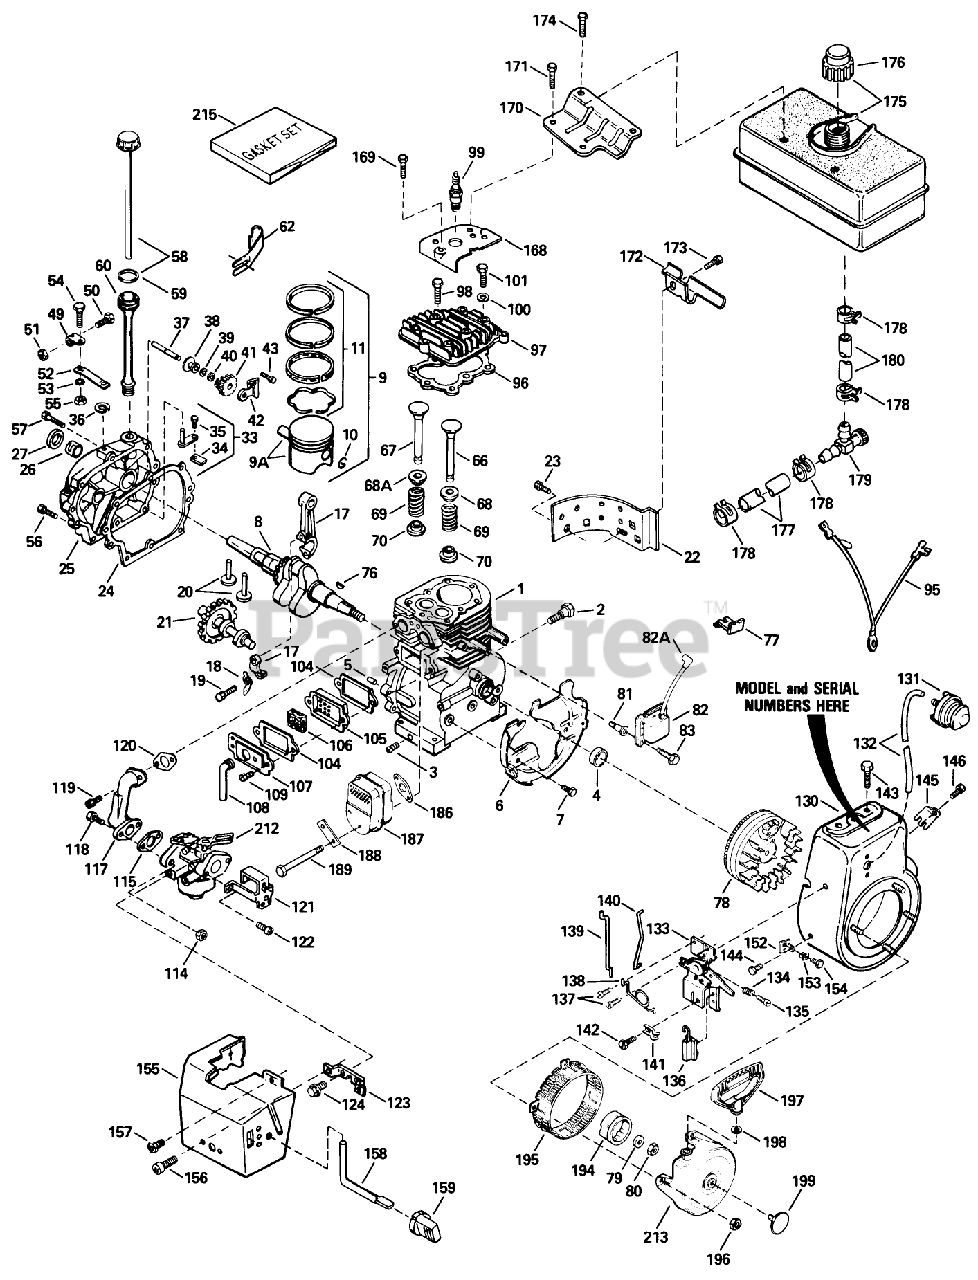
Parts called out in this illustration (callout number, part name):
1	Cylinder Asm (Includes 2, 20, 72)
2	Screw (1/4-20x1/2)
3	Plug-Drain, Oil (SQH 1/4-18)
4	Seal-Oil
5	Pin-Dowel
6	Baffle-Blower Housing
7	Screw (1/4-20x19/32)
8	Crankshaft
9	Piston, Pin Ring Assy.(Std.) (Incl. Ref. #24A, 25 26)
9	Piston, Pin Ring Assy. (.010 oversize) (Incl. Ref. #24A, 25 26)
9	Piston, Pin Ring Assy. (.020 oversize) (Incl. Ref. #24A, 25 26)
9A	Piston Pin Assy. (Std.) (Incl. Ref. #26)
9A	Piston Pin Assy. (.010 oversize) (Incl. Ref. #26)
9A	Piston Pin Assy. (.020 oversize) (Incl. Ref. #26)
11	Ring Set (Std.)
11	Ring Set (.010" OS)
11	Ring Set (.020" OS)
17	Rod Assy., Connecting (Incl. Ref. #26 27)
18	Dipper-Oil
19	Bolt-Rod
20	Lifter-Valve
21	Camshaft (MCR)
22	Extension-Housing, Blower
23	Screw
24	Cylinder Cover Gasket
25	Cover-Cylinder (Includes 71, 75, 80)
26	2025A77 WIZARD ROTA
27	Seal-Oil
33	Rod, Governor (Incl. Nos.62 63)
34	Yoke-Governor
35	Screw (6-40x5/16)
36	Ring-Retaining
37	Shaft-Governor
38	Spool-Governor
39	Washer-Flat
40	Ring-Retaining
41	Gear Assy., Governor (Incl. Ref. #45)
42	Bracket-Gear, Governor
43	Screw (10-24x1/2)
49	Clamp-Lever, Governor
50	Screw
51	Nut-Lock
52	Lever-Governor
53	Washer-Lock
54	Screw
55	Nut-Lock
56	Screw (1/4-20x1-11/16)
57	Screw (1/4-20x1-3/16)
58	Dipstick
59	O-Ring
60	Tube-Fill, Oil
62	Clip-Tube, Fill
66	Valve, Exhaust (Standard)(Incl. No. 9)
66	Valve, Exhaust (1/32" oversize)(Incl. No. 9)
67	Valve, Intake (Std.) (Incl. Ref. #58)
67	Valve, Intake (1/32" oversize) (Incl. Ref. #58)
68	Cap-Spring, Valve
68A	Seal-Intake Valve
69	Spring-Valve
70	Keeper-Spring, Valve
76	Key-Flywheel
77	Clip-Wire
78	Flywheel (W/Ring Gear)
79	Washer-Belleville
80	Nut-Flywheel
82	Solid State ASM
82A	Cover-Spark Plug
83	Screw
95	Ground Wire
96	Gasket-Cylinder Head
97	Head Cylinder
98	Screw (5/16-18x1-1/2)
99	Spark Plug-Resistor (R J19 L M)
100	Washer-Flat
101	Screw (5/16-18x1-25/32)
104	Gasket-Breather
105	Body-Breather
106	Element-Breather
107	Cover-Valve
108	Tube-Breather
109	Screw
114	Nut and Lock Washer (1/4-28)
115	Gasket-Carburetor To Intake Pipe
117	Pipe-Intake
118	Screw (1/4-28x1)
119	Screw (T-30, 5/16-18x1-3/32)
120	Gasket-Intake
121	Bracket-Choke
122	Screw (10-32 x 1/2)
123	Bracket-Carburetor
124	Screw (8-32x27/64)
130	Housing-Blower
131	Primer-Asm
132	Line-Primer
133	Control Assy., Remote Speed (Incl. Ref. #90 thru 93)
134	Spring-Compression
135	Screw
136	Terminal
137	Screw (10-32 x 1/2)
138	Spring-Throttle
139	Link-Governor
140	Link-Throttle
141	Conduit
142	Screw (10-32 x 3/8)
143	Screw (5/16-18x3/4)
144	Screw
145	Screw
146	Screw (8-32 x 3/8)
152	Bracket
153	Grommet
154	Screw (8-32 x 3/8)
155	Cover-Carburetor
156	Screw (10-32 x 3/8)
157	Screw (10-32x1/2)
158	Rod-Choke
159	Knob-Control
168	Cover-Cylinder Head
169	Screw (1/2-20x5/8)
170	Bracket-Tank, Fuel (Black)
171	Screw
172	Bracket-Tank, Fuel
173	Screw (1/4-20x19/32)
174	Screw (1/4-15x7/8)
175	Tank Assy., Fuel (Incl. No. 115)
176	Cap, Fuel
177	Line-Fuel
178	Clamp-Line, Fuel
179	Valve-Shut Off
180	Line-Fuel (8.62)
186	Gasket Exhaust
187	Muffler
188	62513 SNWTHWR W/284
189	Screw
194	Cup-Starter
195	Screen-Starter
196	Nut and Lock Washer (1/4-28)
197	Handle-Starter, Mitten Grip
198	Washer
199	Plug Starter
212	Carburetor (Incl. Ref. #75)
213	Starter-Rewind
215	Gasket Set (Incl. items marked *) Order As Accessory.
